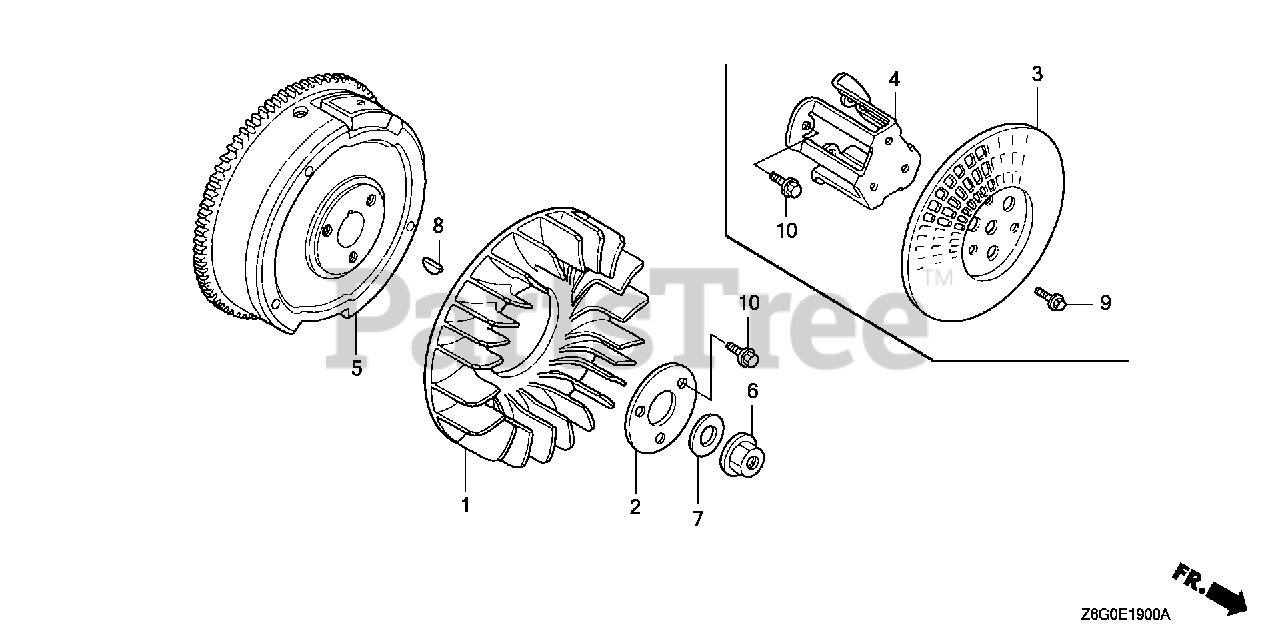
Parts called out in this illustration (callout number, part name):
1	FAN, COOLING
2	PLATE, COOLING FAN SETTING
3	GRID, SCREEN (P.T.O.)
4	HOLDER, SCREEN GRID
5	FLYWHEEL
6	NUT, FLANGE (20MM)
7	WASHER (20MM)
8	KEY, SPECIAL WOODRUFF (25X18)
10	BOLT, FLANGE (8X16) Use from Engine SN 1000016.
